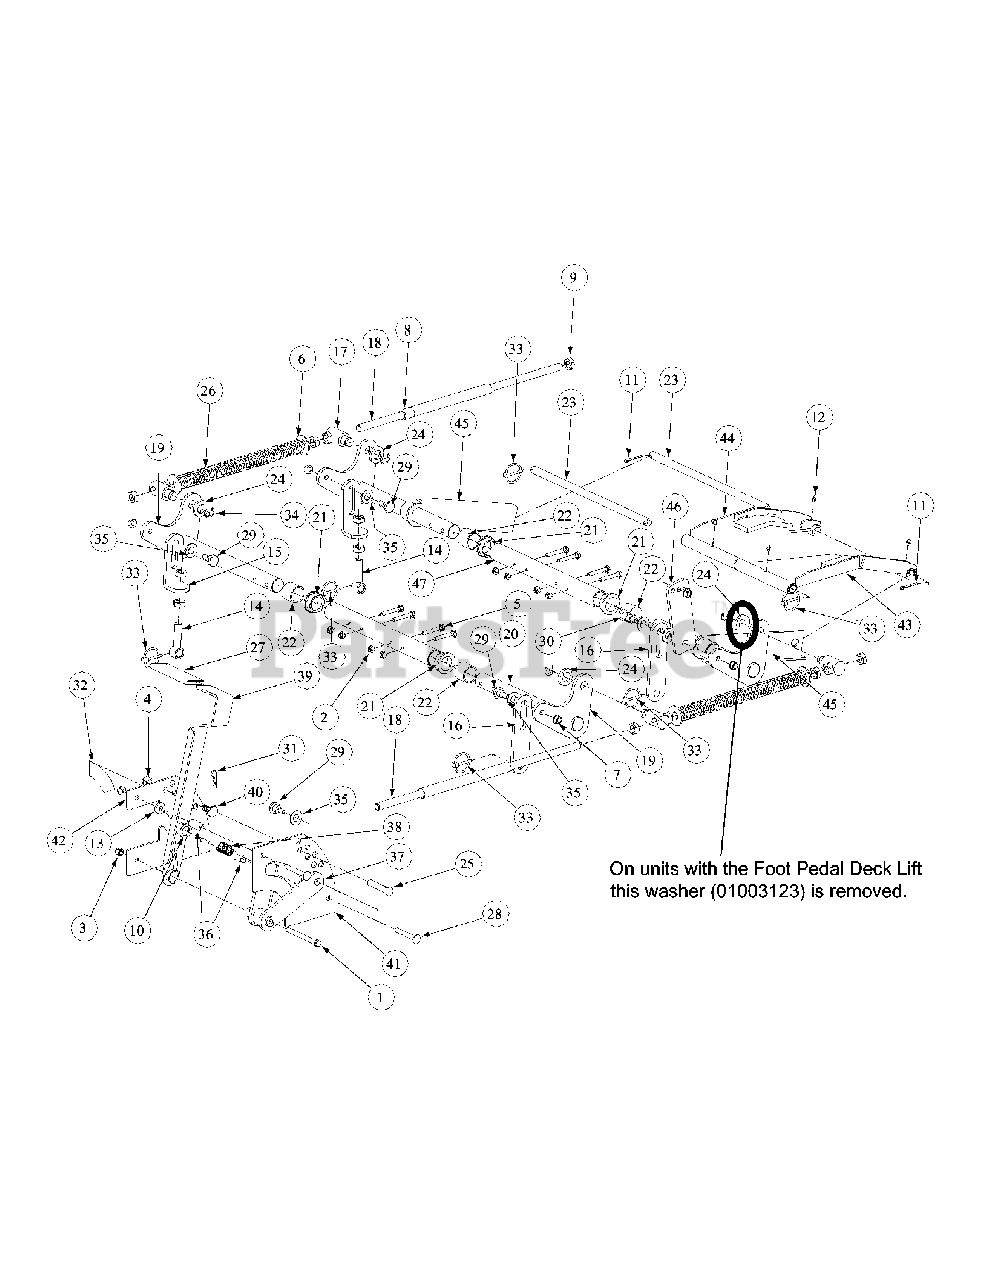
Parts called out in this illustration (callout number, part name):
1	Hex Cap Screw, 3/8-16, 3.75
2	Nut, 5/16-18, Nylock
3	Nylock Insert Lock Nut, 3/8-16
4	Nylock Insert Lock Nut, 1/2-13
5	Hex Cap Screw, 5/16-18 x 2
6	Flat Washer, 5/8
7	Hex Nut, Flange Lock, 3/8-16
8	PVC Hose, 5/8
9	Jam Nut, 5/8-11
10	Flat Washer, .06, .776, 1.25
11	Cotter Pin, 3/16 x 1-1
12	Grease Fitting, 1/4-28 x 3/16
13	Idler Washer
14	Eye Bolt, 5/8ID
15	Eye Bolt Mount Link, 5/8 ID
16	Deck Link
17	Ferule Lift
18	Lift Connector Rod
19	Bellecrank Weldment Lift, Left Hand
20	Bellecrank Weldment Lift, Right Hand
21	Hex Flange Bearing, 1.25 ID
22	Frame Lift Spacer
23	Front Lift Link, Rod Mount
24	Spacer, .812 ID x .268 Lg.
25	Clevis Pin, .500 Dia. x 2.625 Lg.
26	Lift Compression Spring
27	Lift Handle Grip
28	Carriage Bolt, 3/8-16, 2.75
29	Shoulder Screw, 0.625 OD x .437 Lg.
30	Shoulder Screw, 0.625 OD x .830 Lg.
31	Cotter Pin, .148 x 3.00
32	Decal Height Indicator
33	Linch Pin, 3/16 Dia.
34	Clip, 3/4 Dia.
35	Nylon Flat Washer, 5/8
36	Spacer, .39 ID x .63 OD x 1.442
37	Lift Pivot Assembly
38	Lift Handle Spring
39	Lift Handle Assembly
40	Shoulder Screw, 5/8 OD x 0.264
41	Outer Lift Index Plate
42	Inner Lift Index Plate
43	Bearing Lift Brace Assembly, Right Hand
44	Bearing Lift Brace Assembly, Left Hand
45	Front Frame Strut Assembly
46	Lift Link Adjustment
47	Lift Shaft Holder
